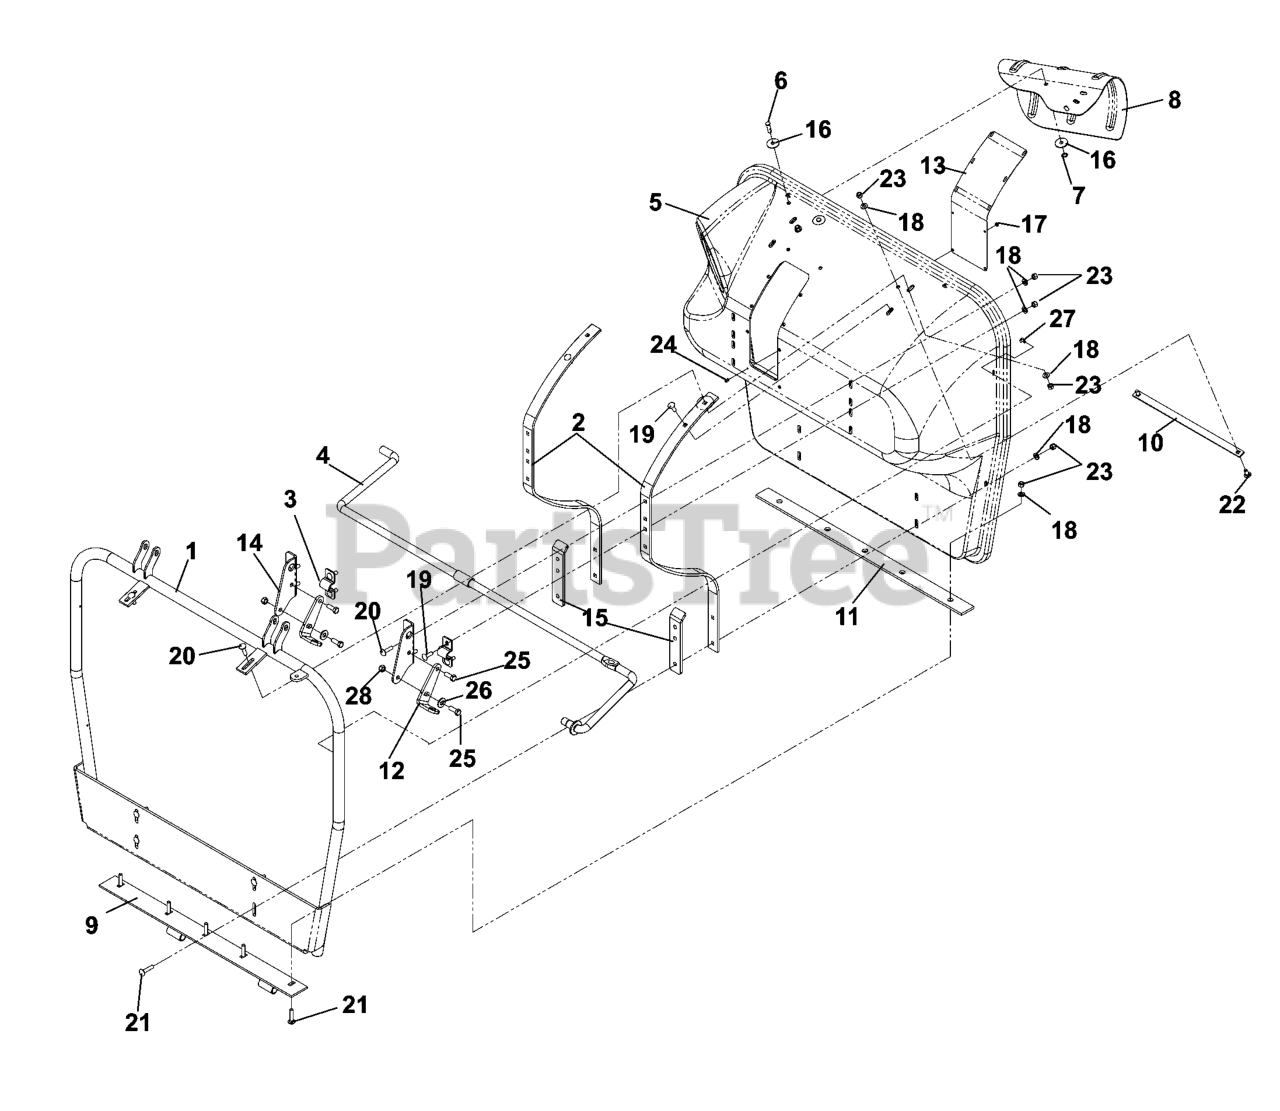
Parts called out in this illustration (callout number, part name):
1	FRONT FRAME WLDT.
4	LIFT SHAFT
5	CLAM SHELL (FRONT)
6	CLEVIS PIN 5/16
7	RETAINER RING
8	DEFLECTOR
9	MOUNT.LOWER.CLAMSHELL
11	CLAMSHELL SPACER
12	BRACKET, SUPPORT
14	BRKT, SUPPORT, UPPER
15	CLAMSHELL SUPPORT PLATE
16	WASHER, FENDER 5/16
17	5/8-11 HEX NUT
18	FLAT WASHER 5/16 SAE
19	RHSSNB 5/16C X 1.0
20	BOLT, CARRIAGE 5/16X1-1/4
21	RHSNB 5/16-18 X 1-1/2 GR 5 ZD
22	BOLT 5/16C X 3/4" CARRIAGE
23	NUT 5/16 NYLOC
24	POP RIVET 5/32 STEEL
25	HCS 3/8C X 1
26	WASHER 3/8 FLAT
27	LARGE DOME RIVET
28	NUT 3/8-16 NYLOC
